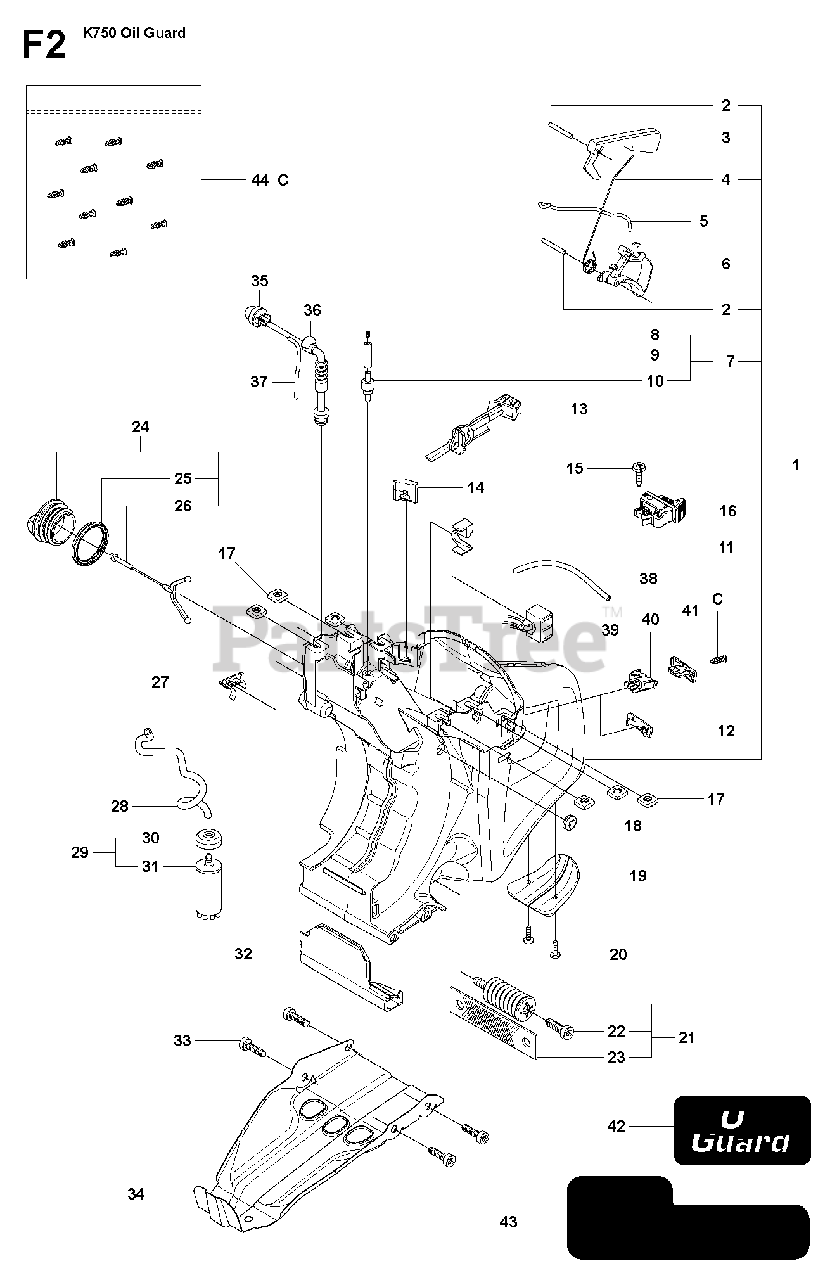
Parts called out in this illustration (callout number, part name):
1	FUEL TANKIncl. 2 - 4, 6 - 7, 11 - 12 Japan only
1	FUEL TANKIncl. 2 - 4, 6 - 7, 11 - 12
2	PARALLEL PIN
3	THROTTLE LOCKOUT
4	SPRING
5	THROTTLE ROD
6	THROTTLE TRIGGER
7	TANK VENT ASSYIncl. 8 - 10
13	CHOKE CONTROL
15	SCREW CCRPANT
16	STOP SWITCH
18	CABLE GROMMET
19	GROUND SUPPORT
20	SCREW CRCSFT
21	ANTIVIBRATION ELEMENTIncl. 22 - 23
22	SCREW ITXSCM
24	TANK CAP ASSYIncl. 25 - 26
28	FUEL HOSE
29	FUEL FILTERIncl. 30 - 31
33	SCREW ITXSCT
35	PURGEJapan only
36	FUEL HOSEJapan only
37	FUEL HOSEJapan only
38	FUEL HOSEOil Guard
39	ELECTRONIC BOXOil Guard
40	HOUSINGOil Guard
41	SWITCHOil Guard
42	LABELOil Guard
43	LABELJapan only
44	KITOil Guard, Incl. 10 pins
